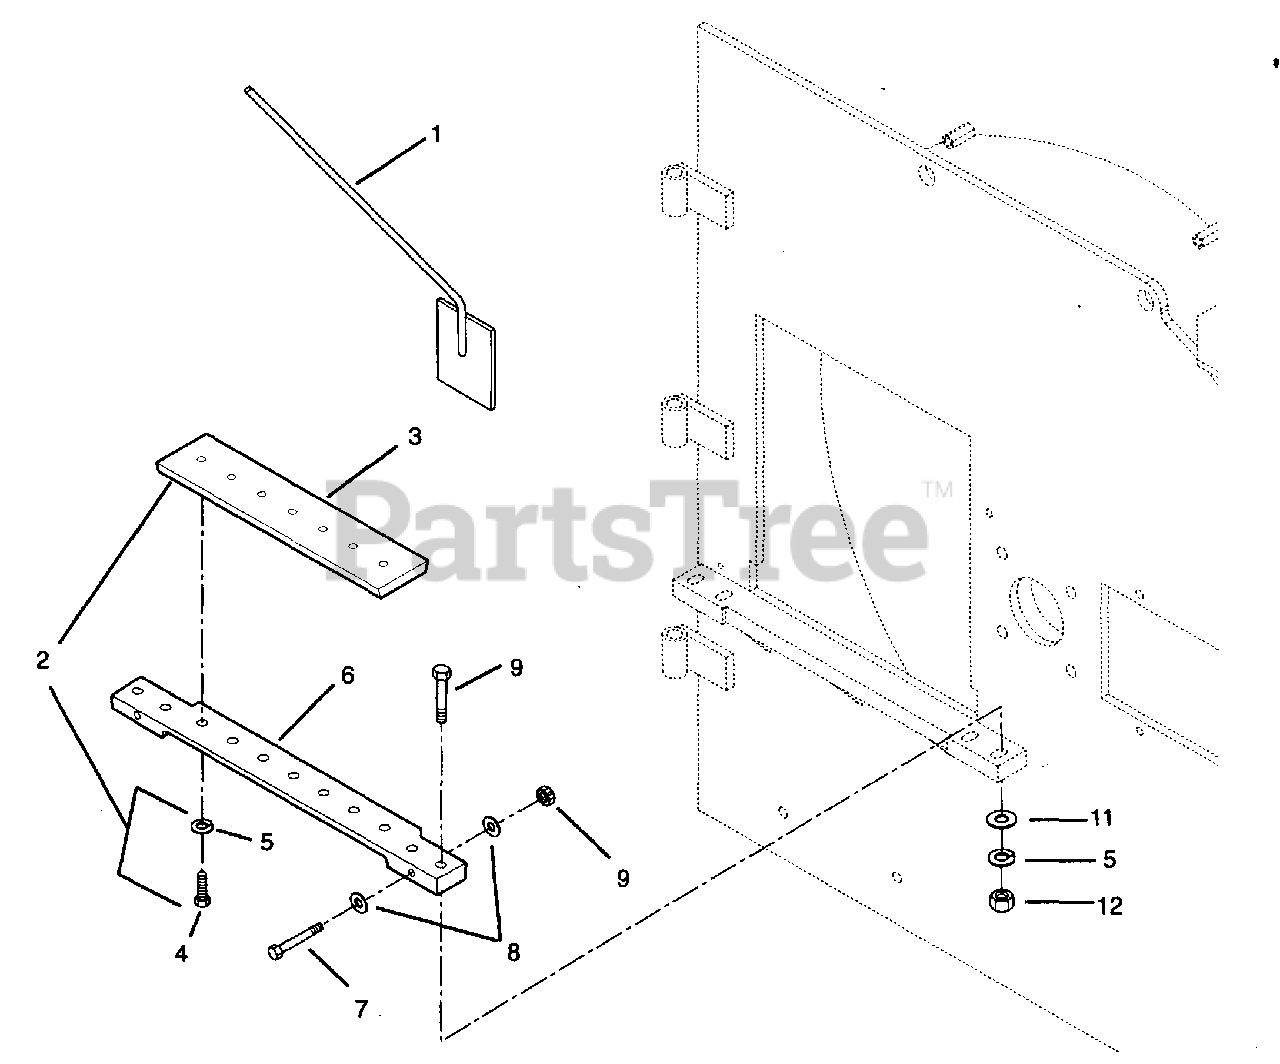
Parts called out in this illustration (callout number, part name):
1	Knife Gauge - 395
2	Bed Knife Kit(Inc. 3,4,5)
3	Bed Knife
4	Bolt-Hex .50-13 x 1.25 Grade 8
5	Washer-Lock .50 Reg.
6	Adjustment Bar
7	Bolt-Hex .38-24 x 2.75 Grade 5
8	Washer-Flat-Hardened .406 x .812 x .075
9	Nut-Locking-Nylon .375-24 Grade 2
10	Bolt-Hex .50-13 x 2.75 Grade 8
11	Washer-Flat-Steel .563 x 1.375 x .109
12	Nut .50-13
